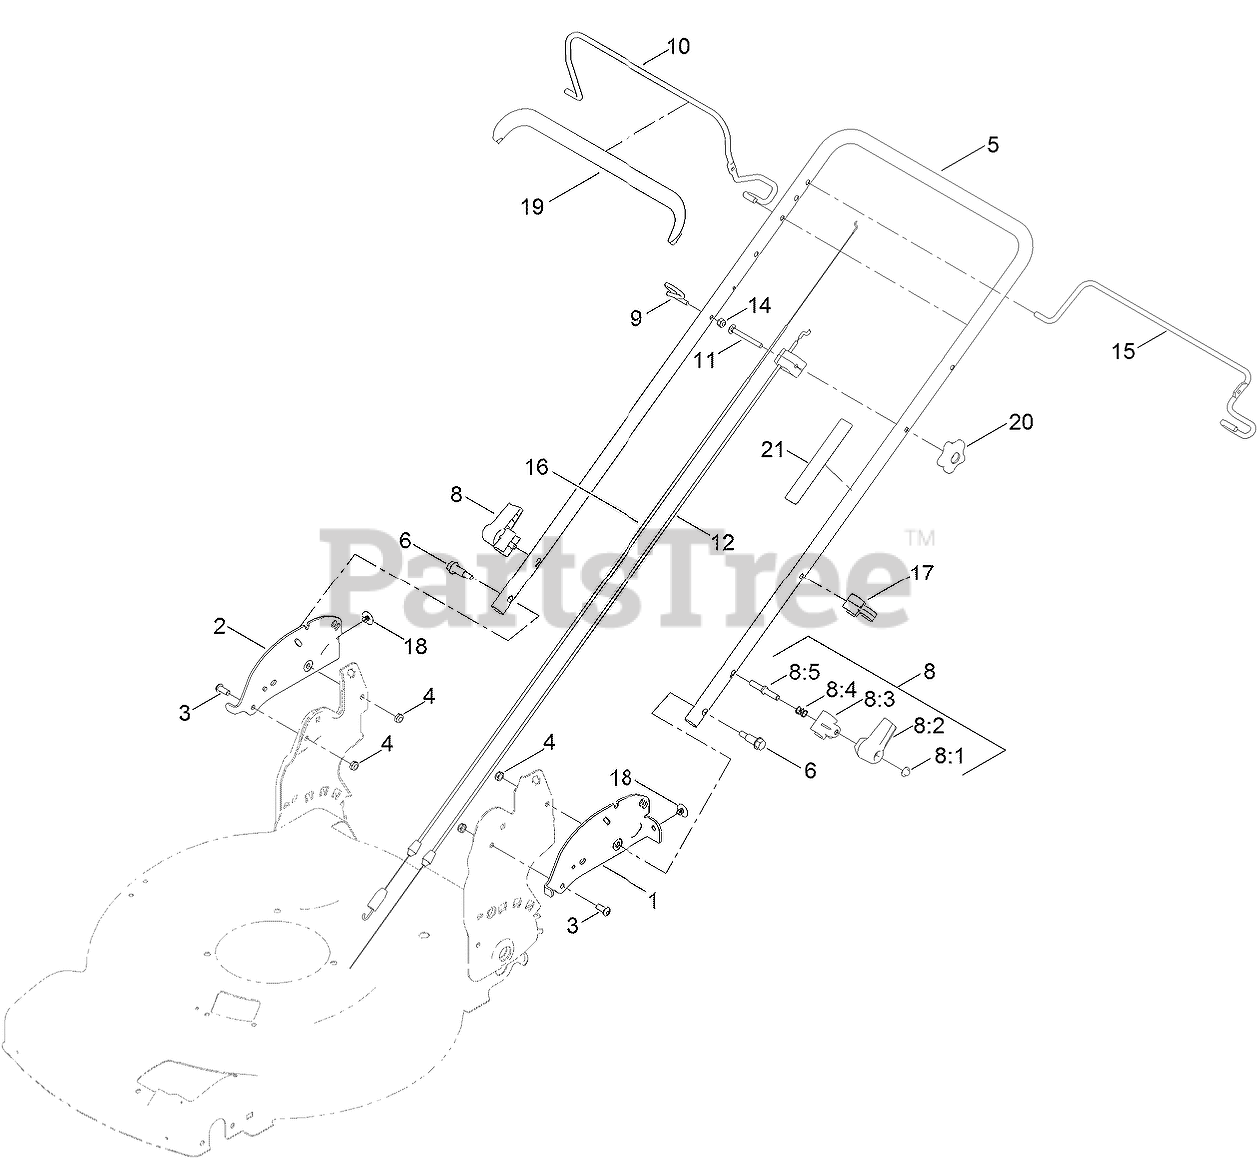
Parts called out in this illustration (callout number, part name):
1	PLATE-HANDLE, LH
2	PLATE-HANDLE, RH
3	SCREW-HSBH
4	NUT-LOCK, NI
6	BOLT-SHOULDER
8	QUICK RELEASE ASM
8:1	NUT-PUSH
8:2	LEVER
8:3	ANCHOR-SPRING
8:4	SPRING-COMPRESSION
8:5	ROD-RELEASE
9	GUIDE-ROPE
10	BAIL-BRAKE
11	SCREW-CARR
12	CABLE-BRAKE, HP
14	NUT-LOCK, NI
15	BAIL-TRACTION
16	CABLE-TRACTION
17	GUIDE-CABLE
18	CLIP-TREE
19	COVER-BAIL
20	KNOB-HANDLE, LOCKING
21	DECAL-TRACTION, ADJUST
